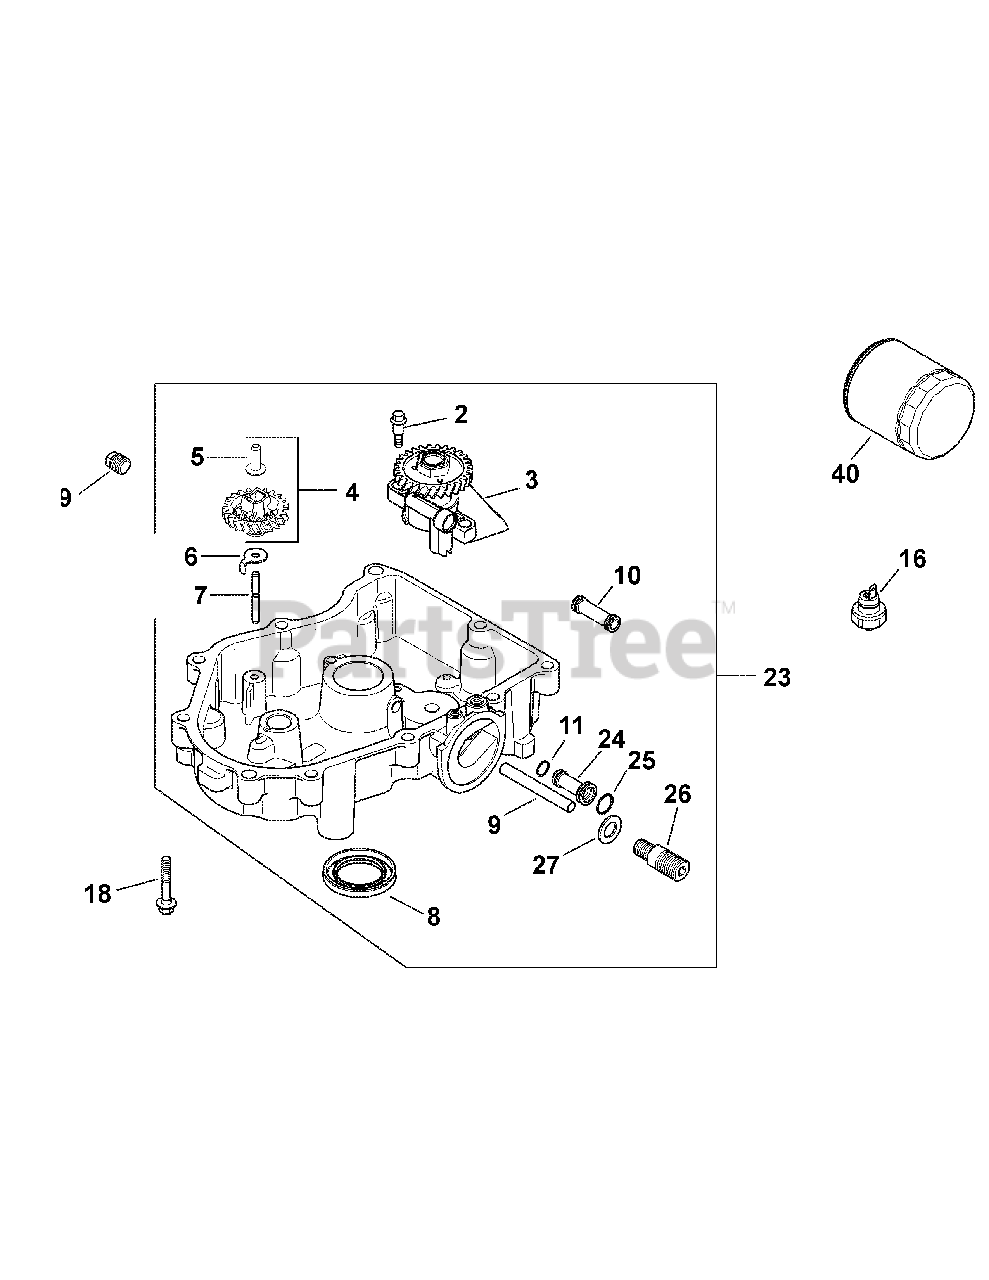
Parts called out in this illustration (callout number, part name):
2	Shd. Thd. Frm. Screw, M6 x .0 x 6.5
3	Oil Pump Assembly
4	Governor Gear Kit w/ Pin
5	Governor Regulating Pin
7	Governor Gear Shaft
9	Oil Feed Tube - Filter To Pan
10	Oil Feed Tube Assembly
11	Oil Pick-Up O-Ring
16	Oil Pressure Switch
18	Flg. Screw, M8 x 1.25 x 45
19	Sq. Hd. PipePlug, 3/8
23	Oil Pan Assembly
24	Oil Feed Tube
26	Oil Filter Nipple
40	Oil Filter
